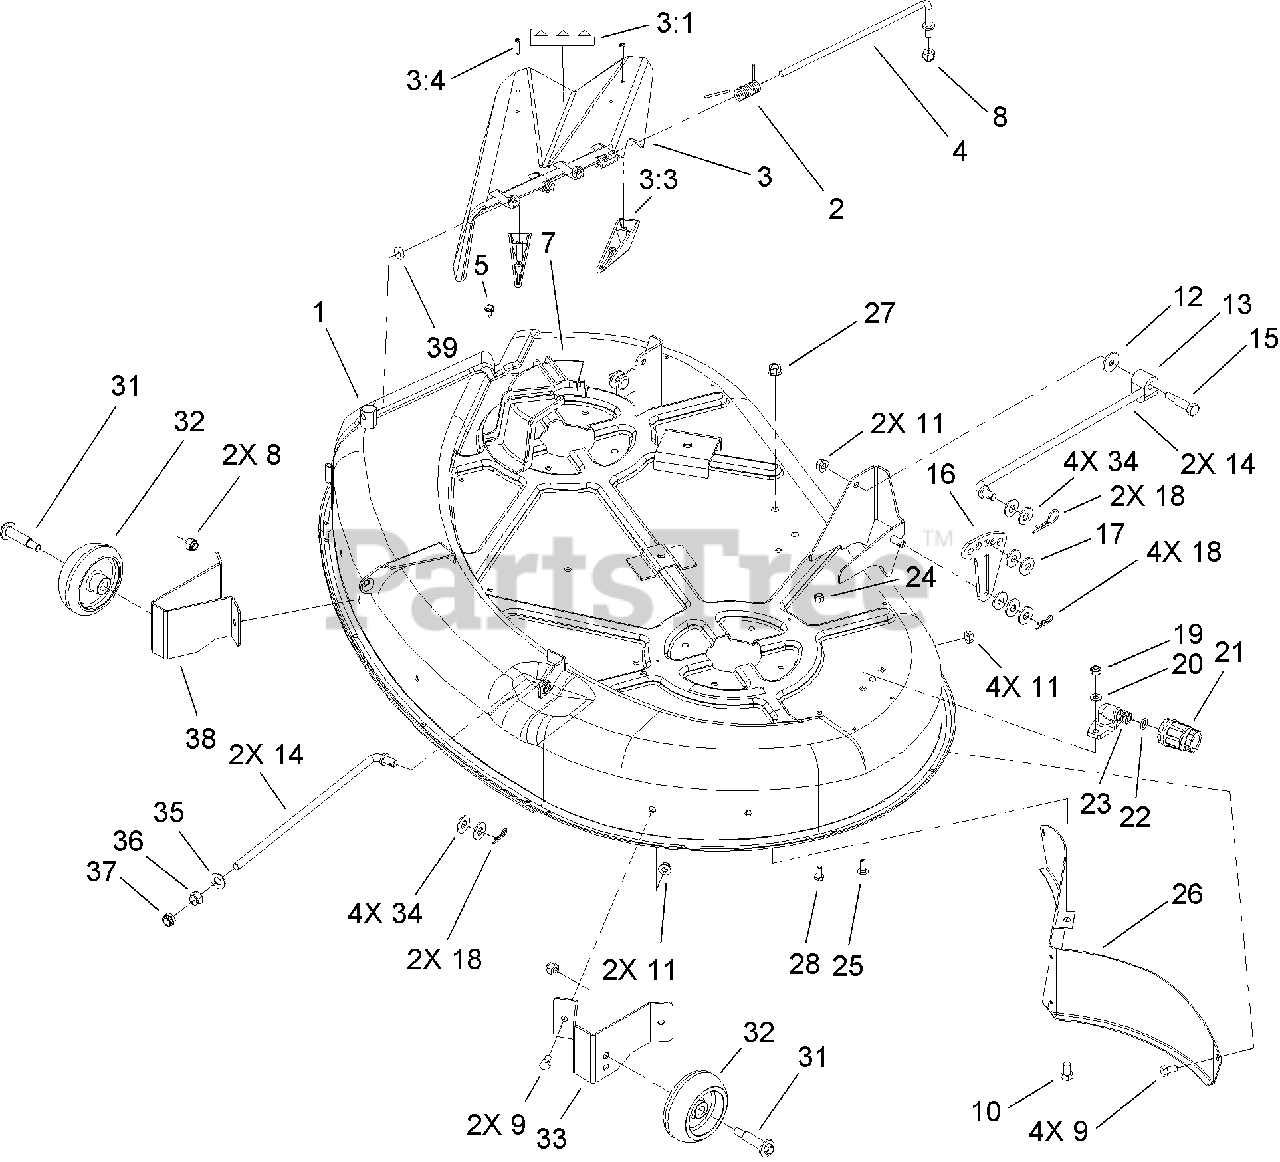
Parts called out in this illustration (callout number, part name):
1	42 INCH DECK ASM
3	DEFLECTOR ASM
3:1	DECAL-DANGER
3:4	SCREW-PPH
4	ROD-PIVOT
7	RH BELT GUIDE-DECK
8	NUT-LOCK, NI
9	SCREW-HH
10	SCREW-HH
12	WASHER-PIVOT
13	TRUNNION-HOC
14	ROD-HANGER
15	BOLT-SHOULDER
16	LINK-ADJUSTING, HOC
17	WASHER-HARDENED
18	PIN-HAIR
19	NUT-LOCK, NI
20	WASHER-FLAT
21	CONNECTOR-HOSE
23	FITTING-WASHOUT
24	NUT-LOCK, NI
25	SCREW-CARR
26	BAFFLE-REAR
28	SCREW-HH
31	BOLT-WHEEL
32	WHEEL-GAGE
33	BRACKET-GAGE WHEEL, FRONT (LH)
34	WASHER-FLAT
35	WASHER-FLAT
36	NUT-HEX
37	NUT-LOCK, NI
38	BRACKET-GAGE WHEEL, FRONT (RH)
